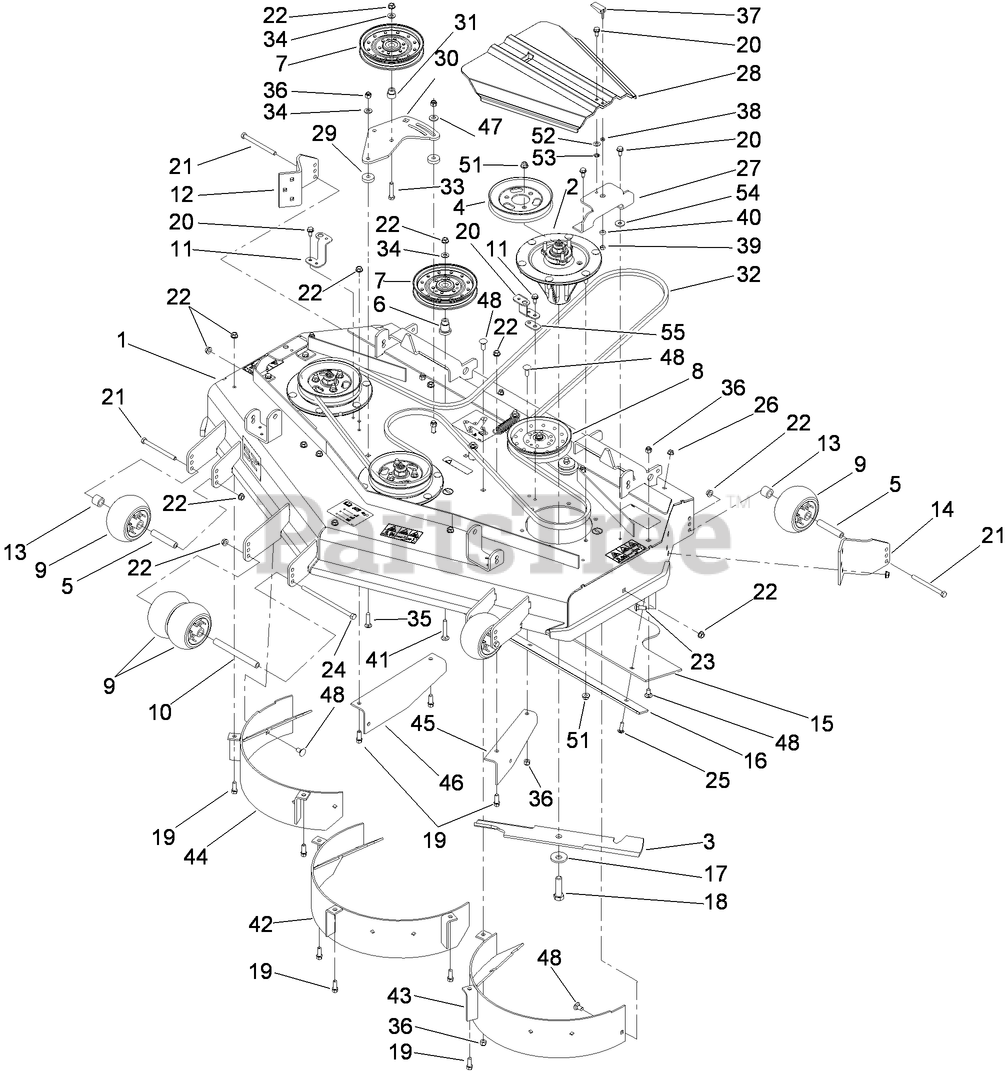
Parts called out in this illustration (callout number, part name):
1	DECK DECAL ASM
2	SPINDLE ASM
3	BLADE-18IN, HI FLOW
4	Pulley
5	TUBE-SPANNER
6	MOUNT-PULLEY
7	Idler-Flat
8	SPRING IDLER ASM
9	ROLLER-SCALP, ANTI
10	SPACER-WHEEL
11	BRACKET-COVER, TALL
12	MOUNT-ANTI SCALP, RH
13	TUBE-SPACER
14	MOUNT-ANTI SCALP, LH
15	DEFLECTOR-RUBBER
16	SKID-SKIRT
17	Washer-Blade Bolt, Heavy
18	SCREW-BLADE
19	SCREW-HWH
20	SCREW-HWHTF
21	SCREW-HH
22	NUT-HHF, WHIZ
23	BOLT-CARR
24	SCREW-HH
25	SCREW-CARR
26	NUT-HF
27	BRACKET-BELT COVER
28	COVER-BELT
29	Spacer
30	PLATE-IDLER
31	BUSHING-IDLER
32	BELT-V
33	SCREW-HH
34	WASHER-FLAT
35	SCREW-CARR
36	NUT-LOCK, NI
37	HANDLE-LATCH, SWELL
38	WASHER
39	NUT-LOCK, HH
40	BUSHING-LATCH, SWELL
41	SCREW-CARR
42	BAFFLE-CENTER
43	BAFFLE-LH
44	BAFFLE-RH
45	BAFFLE-TRAILING
46	BAFFLE-TRAILING
47	WASHER-BELLEVILLE
48	SCREW-CARR
51	NUT-HF, NI
52	WASHER-THRUST
53	NUT-PUSH
54	WASHER
55	SPACER-BELT COVER
